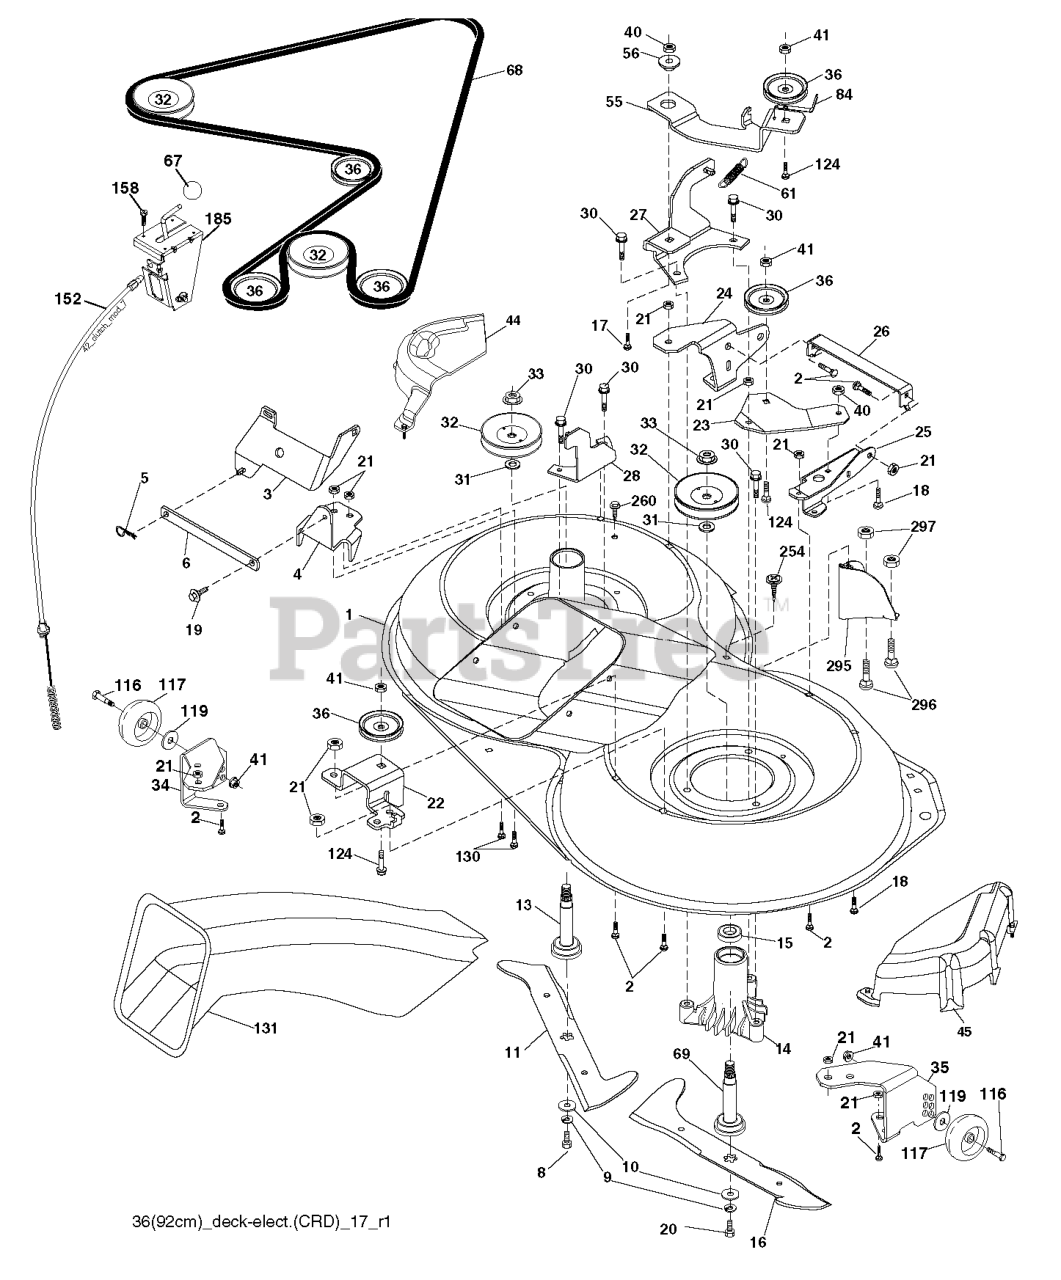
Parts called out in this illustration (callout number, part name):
2	RP BOLT 5/16-18 X3/4 ZN/YEL GR
3	BRACKET.ASM.BAR.SWAY.CHASS
5	RETAINER-SPRNG RB
6	BAR.SWAY.92.CRD
8	BOLT.3/8-24X1.25 GR8
9	LOCKWASHER
10	WASHER.BLADE
13	SHAFT ASM VENT
14	HOUSING.MANDREL.VENTED (MACHD)
17	BOLT.3/8-14X1.25
19	BOLT SHD 5/16-18
20	BOLT.3/8-24X1.25GR8. LHTHRD
21	LOCKNUT
22	BRACKET.SUPT.IDLER.REAR.RH
26	SUPPORT
30	SCREW, WASHER HEAD
31	WASHER.SPACER.MANDREL
32	PULLEY MANDREL
33	NUT.FLANGE.LOCK.TOP
36	PULLEY.IDLER.4.25
41	NUT LOCK FLG 3/8-16 UNC
55	ARM.IDLER.92 CRD.2006
56	SPACER.RETAINER.MOWER
61	SPRING
67	KNOB T (3/8 HOLE)
68	BELT.DRIVE.92CM.CRD.2006
69	SHAFT.ASM.W/LWR.BRG.RH.THREAD
84	KEEPER, BELT IDLER
116	BOLT.SHOULDER.3/8-16X3-5/8.
117	RP WHEEL. GUAGE RALLY
119	WASHER
124	BOLT.3/8-16X1.50
130	BOLT.CARR.SQNK.5/16-18UNC.X3/4
131	CHUTE BAGGER
158	SCREW
185	HEAD ASM. CABLE CLUTCH
254	SCREW 3/8-16X1
260	SCREW 3/8-16X1/2
296	BOLT
297	NUT CENTERLOCK
